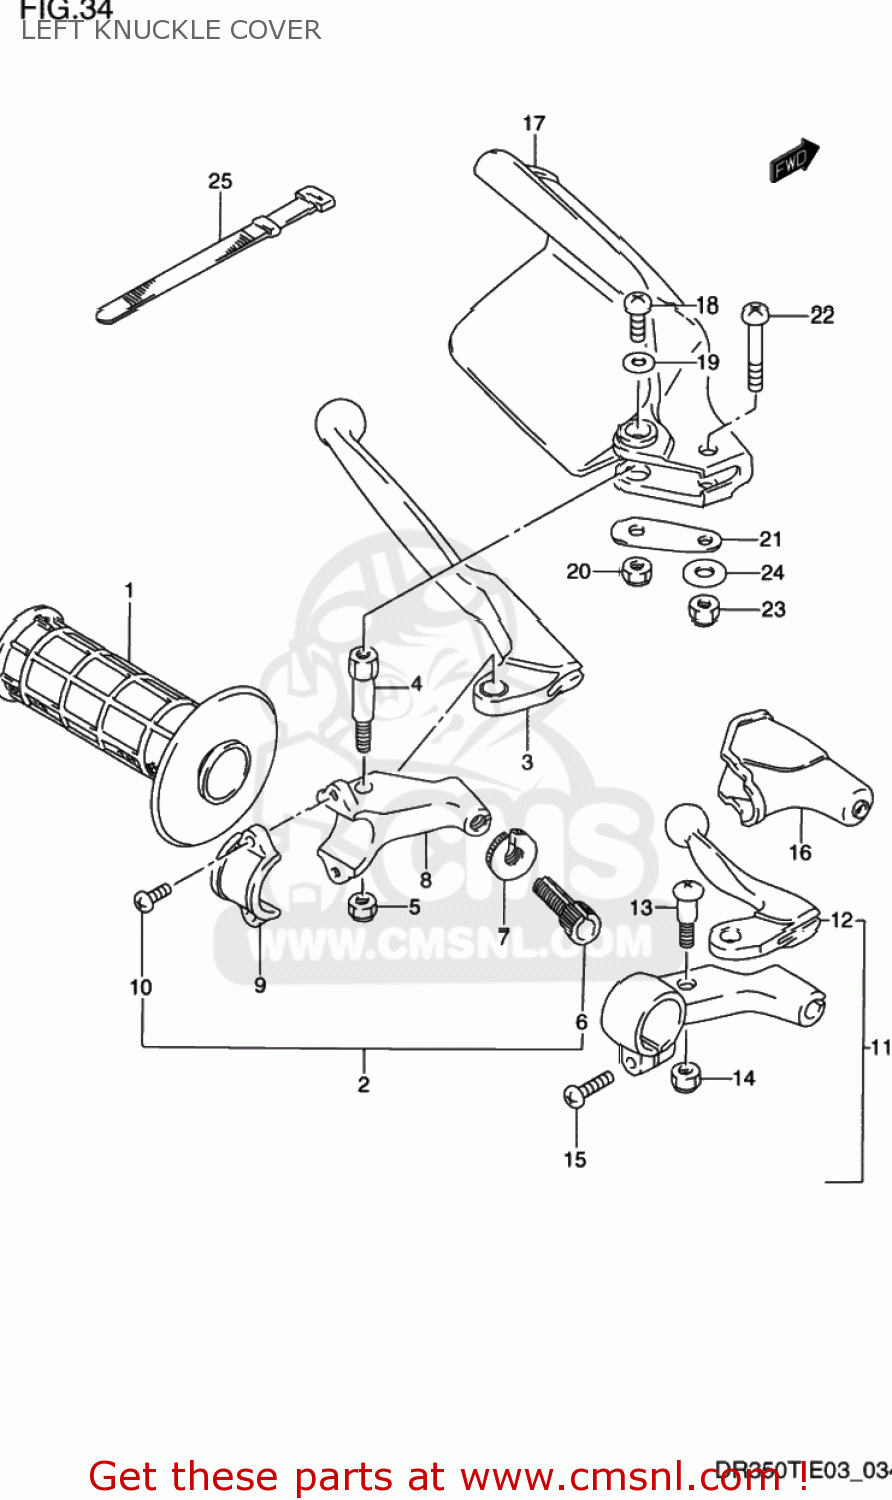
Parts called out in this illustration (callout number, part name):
1	GRIP,L
2	LEVER ASSY,CLUTCH
3	LEVER,CLUTCH
4	BOLT,LEVER SET
5	NUT 6MM
6	ADJUSTER,CABLE
7	NUT,LOCK
8	HOLDER,CLUTCH LEVER
9	BRACKET,CLUTCH LEVER HOLDER
10	SCREW(5X14)
11	LEVER ASSEMBLY,DECOMPRESSION
12	LEVER,DECOMP
13	BOLT,LEVER PIVOT
14	NUT
15	SCREW
16	COVER,DECOMP LEVER DUST
17	COVER,KNUCKLE,L
18	SCREW
19	WASHER (5.5X16X1.2)
20	NUT 6MM
21	PLATE,KNUCKLE COVER,L LWR
22	SCREW
23	NUT 6MM
24	WASHER (6.5X17X1.6)
25	CLAMP(L:120)
